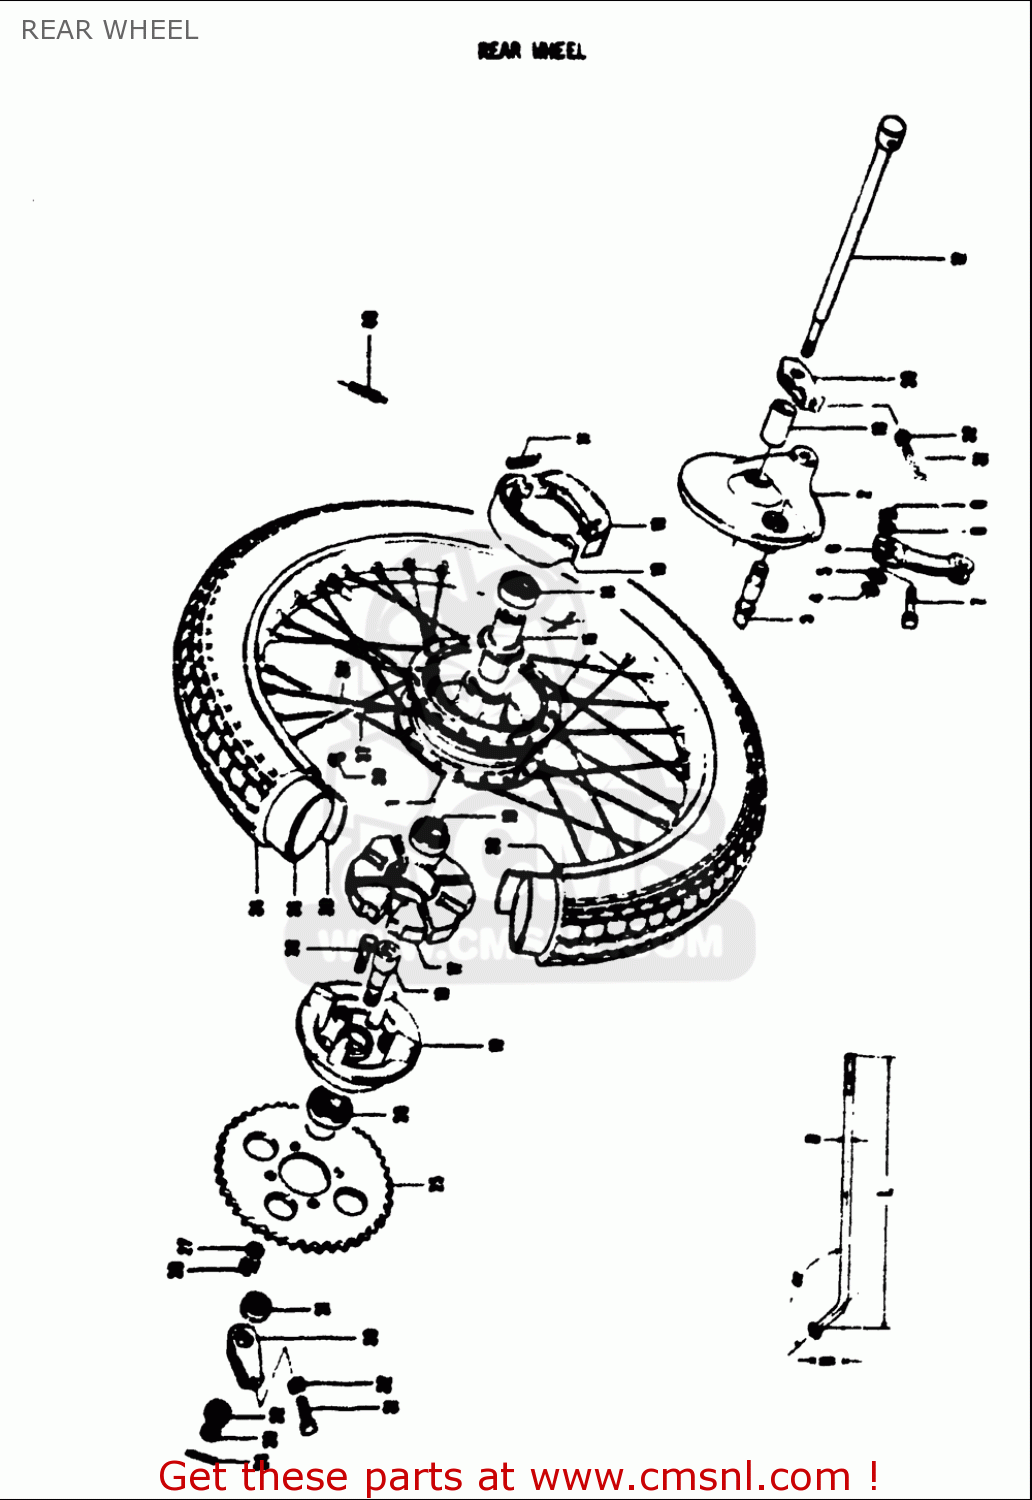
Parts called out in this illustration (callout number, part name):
4	O RING(D:2.5,ID:11.4)
5	WASHER(12.5X20X1)
6	LEVER,RR BRAKE CAM
7	BOLT(6X31)
8	WASHER
9	NUT
11	SPRING(L:35.8)
13	SPACER(15.2X22X26)
14	BEARING
16	BEARING
17	ABSORBER ASSY,HUB SHOCK
20	BEARING
22	NUT
23	NUT 12MM
24	PIN
25	SPROCKET,RR(NT:41)
26	BOLT 8X28
27	WASHER,LOCK
28	NUT
31	BOLT(6X38)
32	NUT
33	RIM,FR WHEEL 1.60X18
35	TUBE ASSY,WHEEL INNER
36	SPOKE SET,RR
